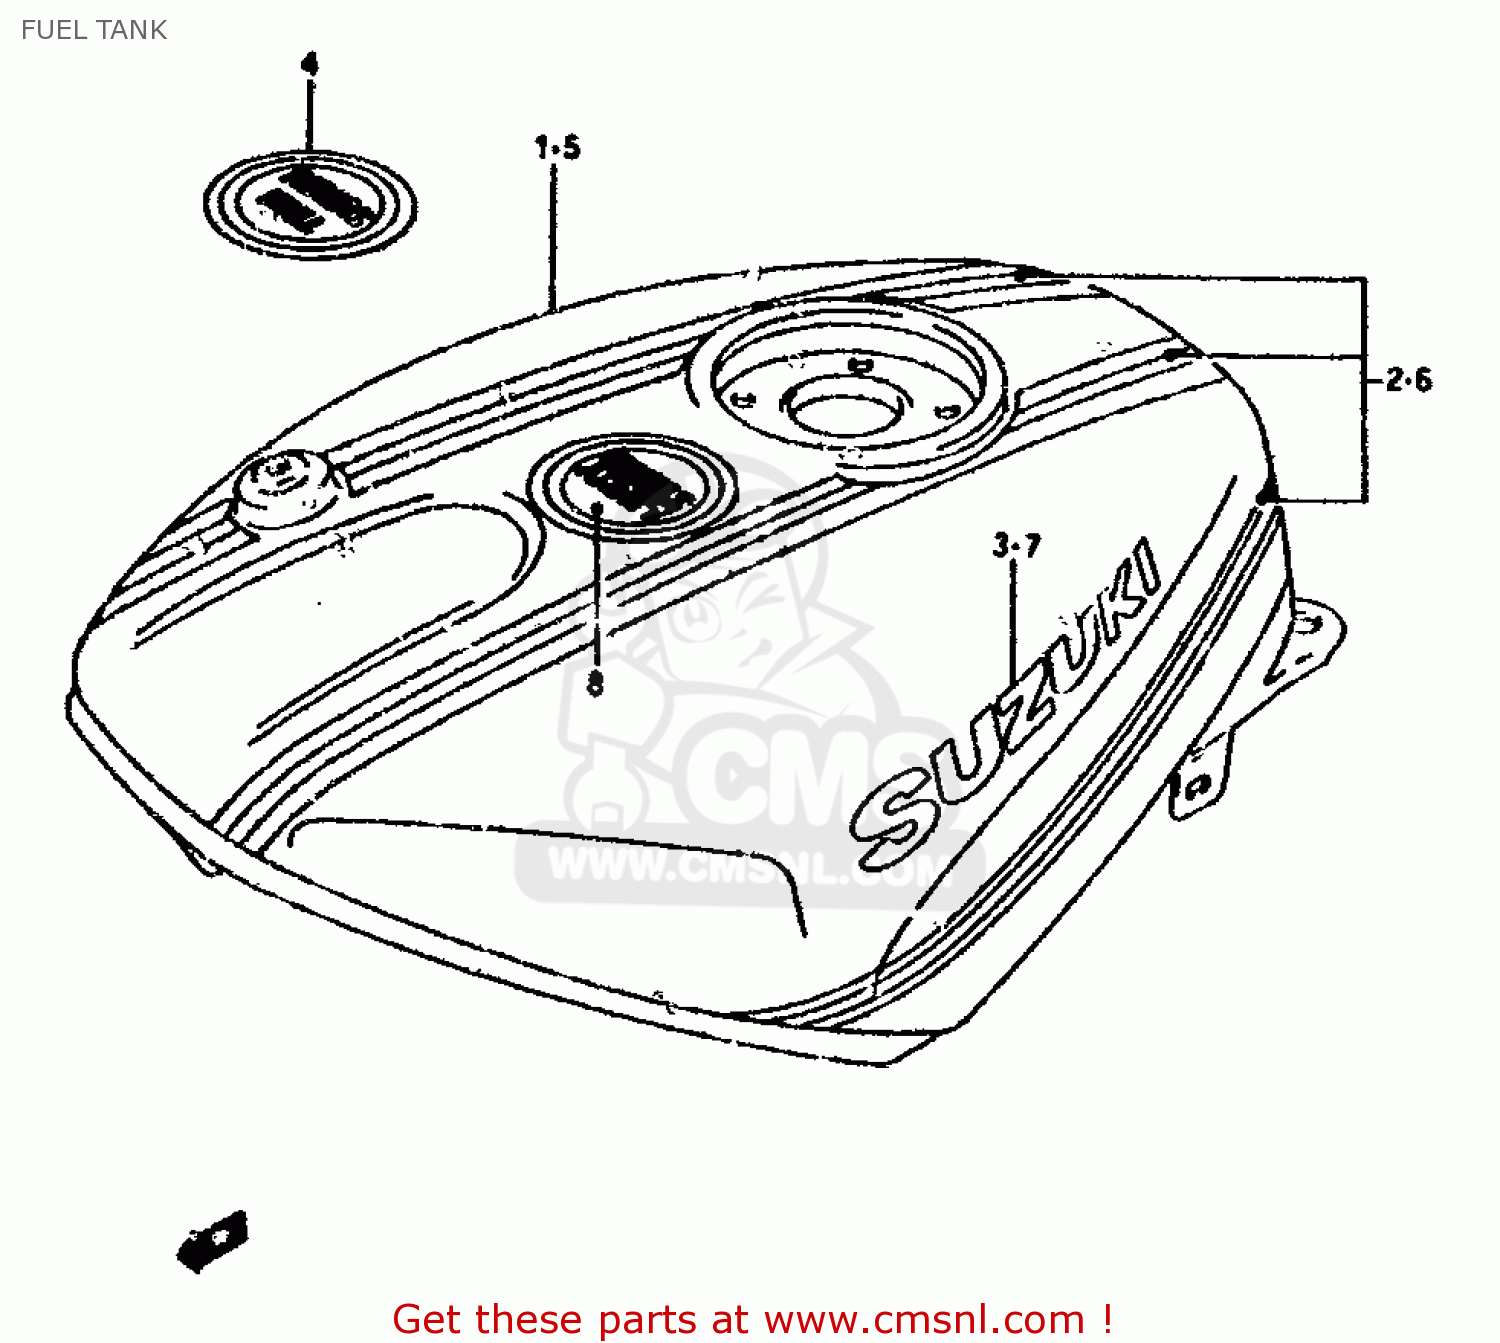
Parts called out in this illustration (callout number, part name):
1	TANK ASSY, FUEL
2	TAPE SET, FUEL TANK
3	EMBLEM (WHITE)
4	EMBLEM, "T-SUZUKI"
5	TANK ASSY, FUEL
6	TAPE SET, FUEL TANK
7	EMBLEM (WHITE)
8	EMBLEM, "L-STRIKE"
